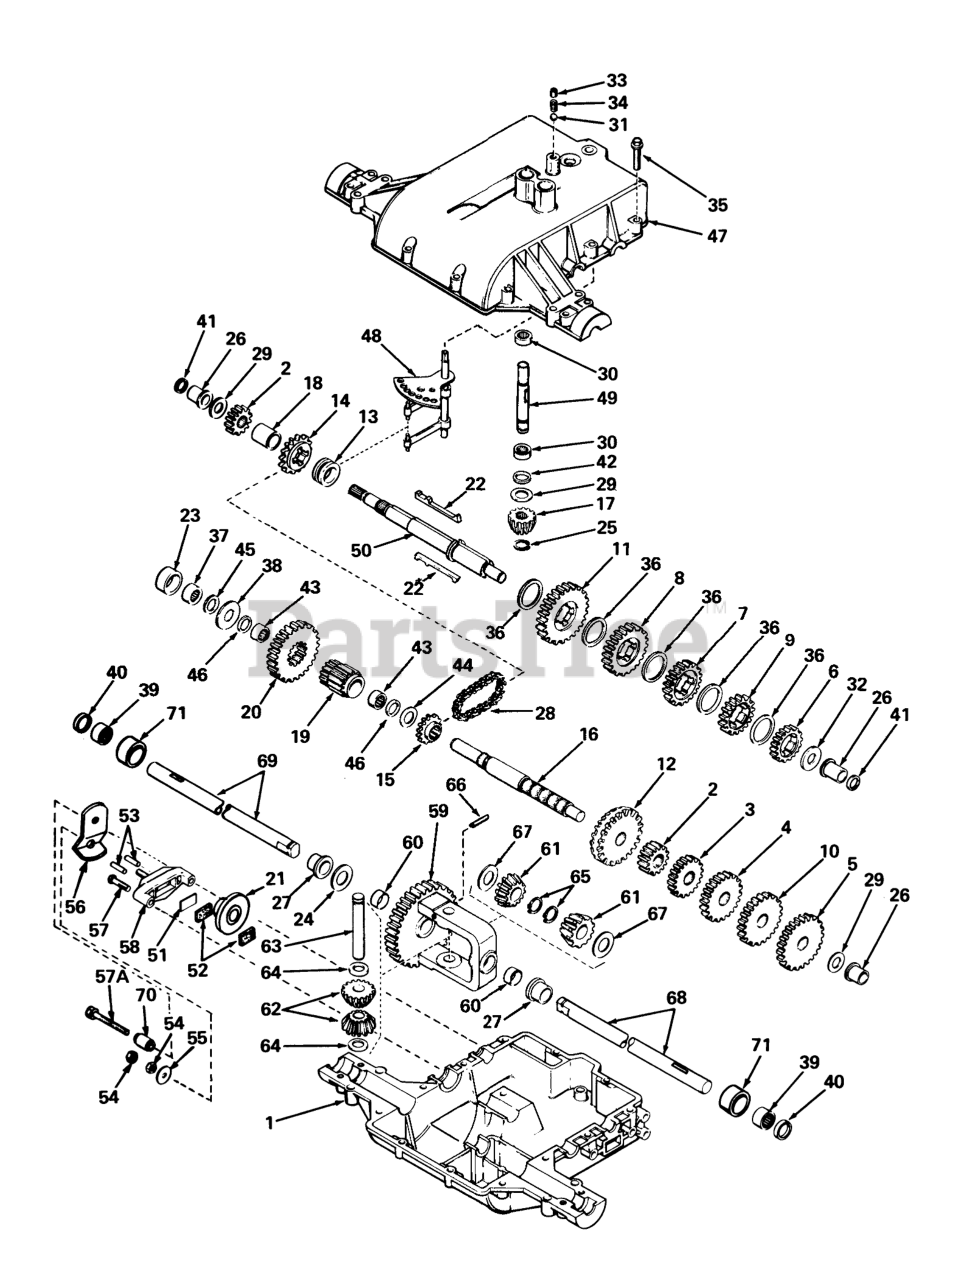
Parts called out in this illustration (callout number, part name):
1	Case, Transaxle
2	Gear-Spur 15 Teeth
3	Gear, Spur (20 teeth)
4	Gear, Spur (25 teeth)
5	Gear, Spur (30 teeth)
6	Gear-Spur 20 teeth
7	Gear, Spur (25 teeth)
8	Gear, Spur (30 teeth)
9	ASpur Gear (22 Teeth)
10	Gear, Spur (28 teeth)
11	Gear-Spur, 35 Teeth
12	Gear, Bevel (42 teeth)
13	Collar-Shift
14	Sprocket-18 Teeth
15	Sprocket-9 Teeth
16	Shaft-Counter
17	Bevel Pinion-Input
18	Spacer
19	Pinion-Output
20	Gear-Output
23	Spacer
24	Washer
25	Ring-Retainer
26	Bushing, Flanged
27	Bronze Bearing
28	Chain-Roller #41
29	Washer
30	Bearing-Needle
31	Ball-Steel
32	Washer
33	Screw-Set
34	Spring
35	Ring Set (.020 O S)
36	Washer
37	Bearing-Needle
38	Washer-Flat
39	Bearing-Cartridge
40	Seal Oil
41	Ring-Square Cut
42	O Ring
43	Bearing-Needle
44	Washer-Flat
45	Ring-Square Cut
46	Ring-Square Cut
47	Cover, Transaxle
48	Rod & Fork Assembly
49	Shaft, Input
50	Shaft, Brake
51	Brake Pad Plate
52	Brake Pad
53	Dowel Pin
54	Locknut
55	Washer
56	Lever-Brake
57	Ring Set (.020 O S)
57A	Screw-Hex. Flange
58	Holder-Brake Pad
59	Gear Assy., Differential (Incl. 2 of No. 60)
60	Bushing
61	Bevel Gear
62	Gear Pinion
63	Drive Pin
64	Thrust Washer
65	Snap Ring
66	Pin-Roll
67	Washer
68	Axle (14-7/8" long)
69	Axle (13" Long)
70	Spacer
71	Sleeve
